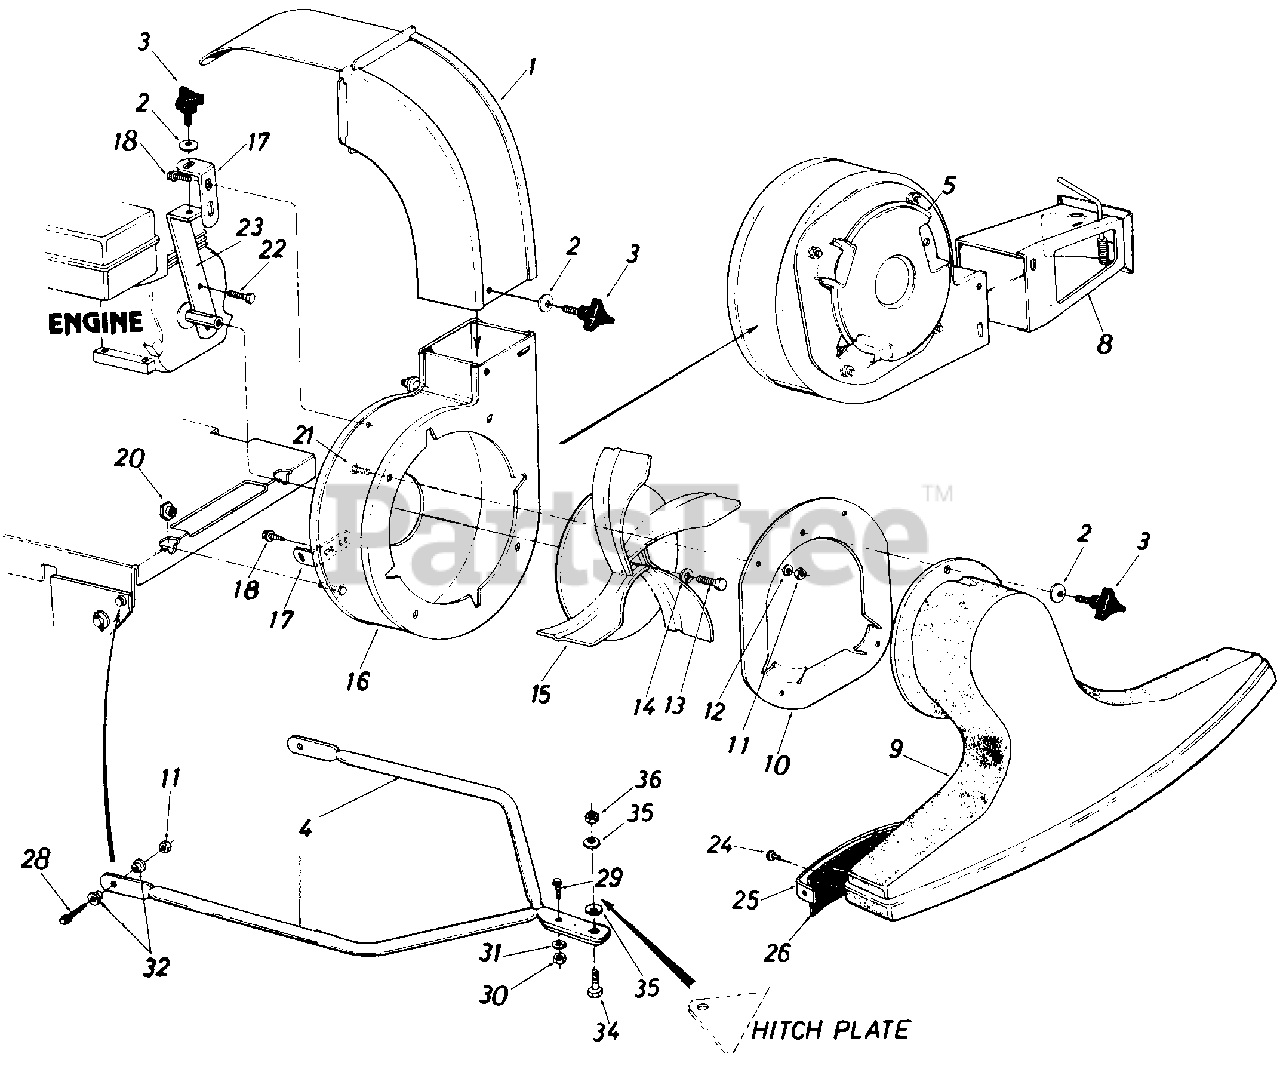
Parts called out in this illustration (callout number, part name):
3	3-Arm Thumb Scr. 5/16-18 x .75" Lg.
10	Nozzle Plate Ass'y.
11	Hex Nut 5/16-18 Thd.*
12	L. Wash. 5/16" I.D.
13	Hex Bolt 3/8-24 x 1.25" Lg.*
14	L.-Wash. 3/8" I.D. H.D.
15	Air Vane Plate Ass y.
16	Blower Housing Complete
20	Hex Shoulder Nut .50 I.D.
21	Carriage Bolt 5/16-18 x .62" Lg. *
22	Hex Locking Bolt 5/16-24 x .75" Lg.
28	Hex Bolt 5/16-18 x 1.00" Lg.*
29	Truss Mach. Scr. 1/4-20 x .75" Lg.*
30	Hex Nut 1/4-2 Thd.*
31	L.-Wash. 1/4" I.D.*
32	Shoulder Spacer
34	Shld. Bolt .496 Dia.
35	Belleville Wash. .39 I.D. x 1.12 O.D.
36	Hex Jam L-Nut 3/8-16 Thd.
